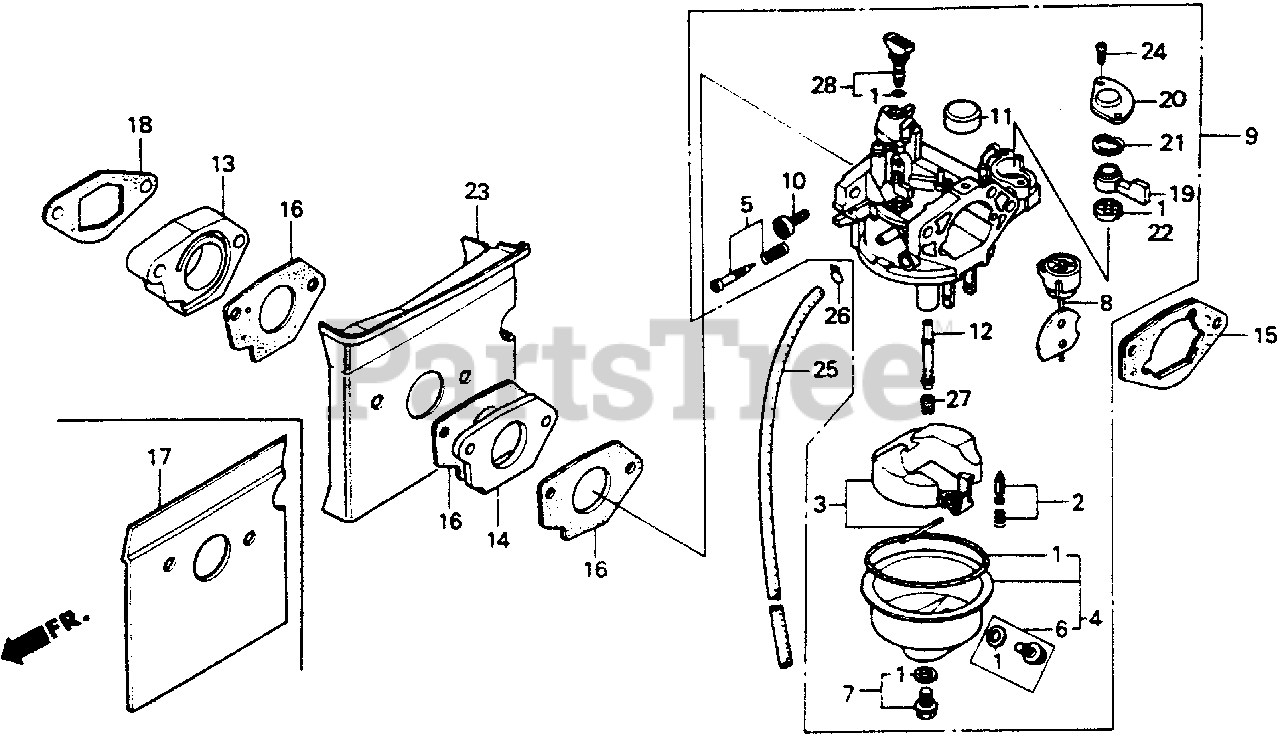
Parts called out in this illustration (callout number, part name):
1	GASKET SET
1	GASKET SET (EXC. 16173-001-004) (EXCEPT 16173-001-004)
2	VALVE SET, FLOAT
4	CHAMBER SET, FLOAT
5	SCREW SET, PILOT
6	SCREW SET, DRAIN
7	SCREW SET
9	CARBURETOR ASSY. (BB36A A)
9	CARBURETOR ASSY. (BB36A B)
9	CARBURETOR ASSY. (BB36A C)
10	SCREW, THROTTLE STOP
11	CAP, CHOKE DUST
12	NOZZLE, MAIN
13	INSULATOR, CARBURETOR
14	INSULATOR, CARBURETOR
15	SPACER, CARBURETOR
16	GASKET, CARBURETOR
18	GASKET, INSULATOR
19	LEVER, VALVE
20	PLATE, LEVER SETTING
21	SPRING, PETCOCK LEVER
22	GASKET, PETCOCK
23	GUIDE, AIR
24	SCREW, PAN (3X8)
25	BULK HOSE, FUEL (4.5X3000) (4.5X100)
26	CLIP, TUBE (B8)
27	JET, MAIN (#85)
27	JET, MAIN (#82)
27	JET, MAIN (#88)
28	JET SET, PILOT (#40)
